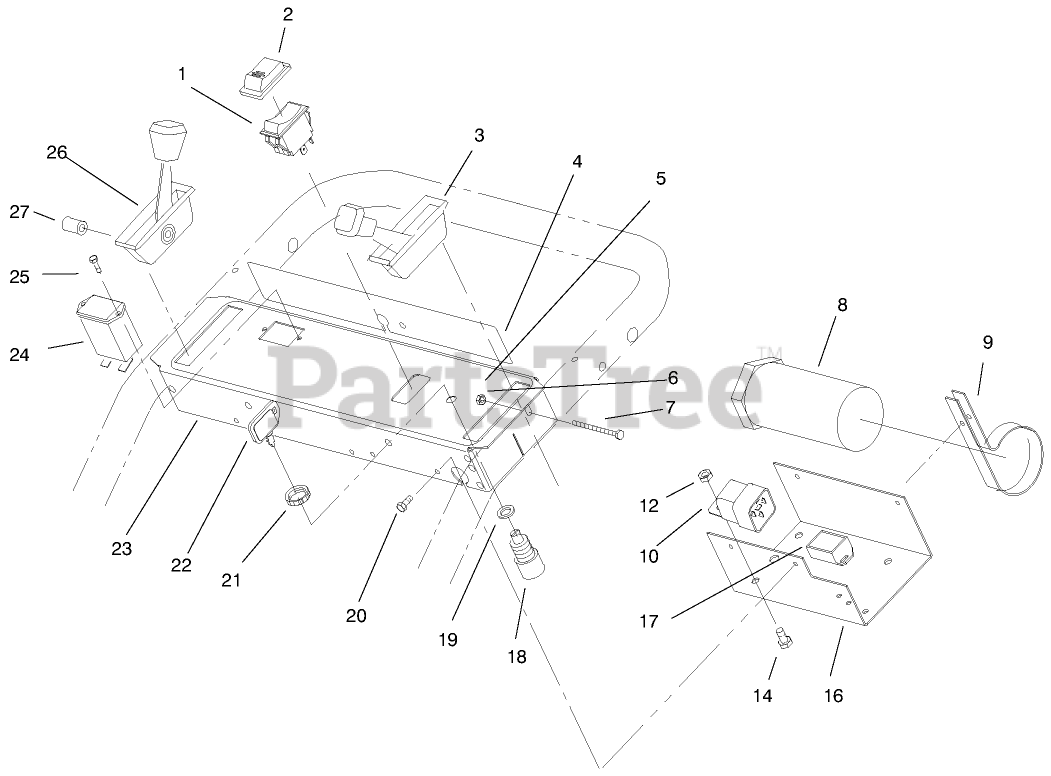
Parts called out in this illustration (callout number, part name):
1	SWITCH
2	BOOT-SWITCH
3	CONTROL-THROTTLE
4	DECAL-WARNING
5	DECAL - CONTROL PANEL
6	NUT-LOCK, NI
7	SCREW-SHH
8	TUBE-MANUAL
9	CLAMP-R
10	RELAY
12	NUT-LOCK, NI
14	SCREW-HH
16	PANEL-BOTTOM
17	MODULE
18	SWITCH-STARTER
19	WASHER-TOOTH, INTERNAL
20	SCREW-HWHTF
21	NUT-HH
22	KEY-IGNITION
23	PANEL - CONTROL
24	HOURMETER
25	SCREW-HWH
